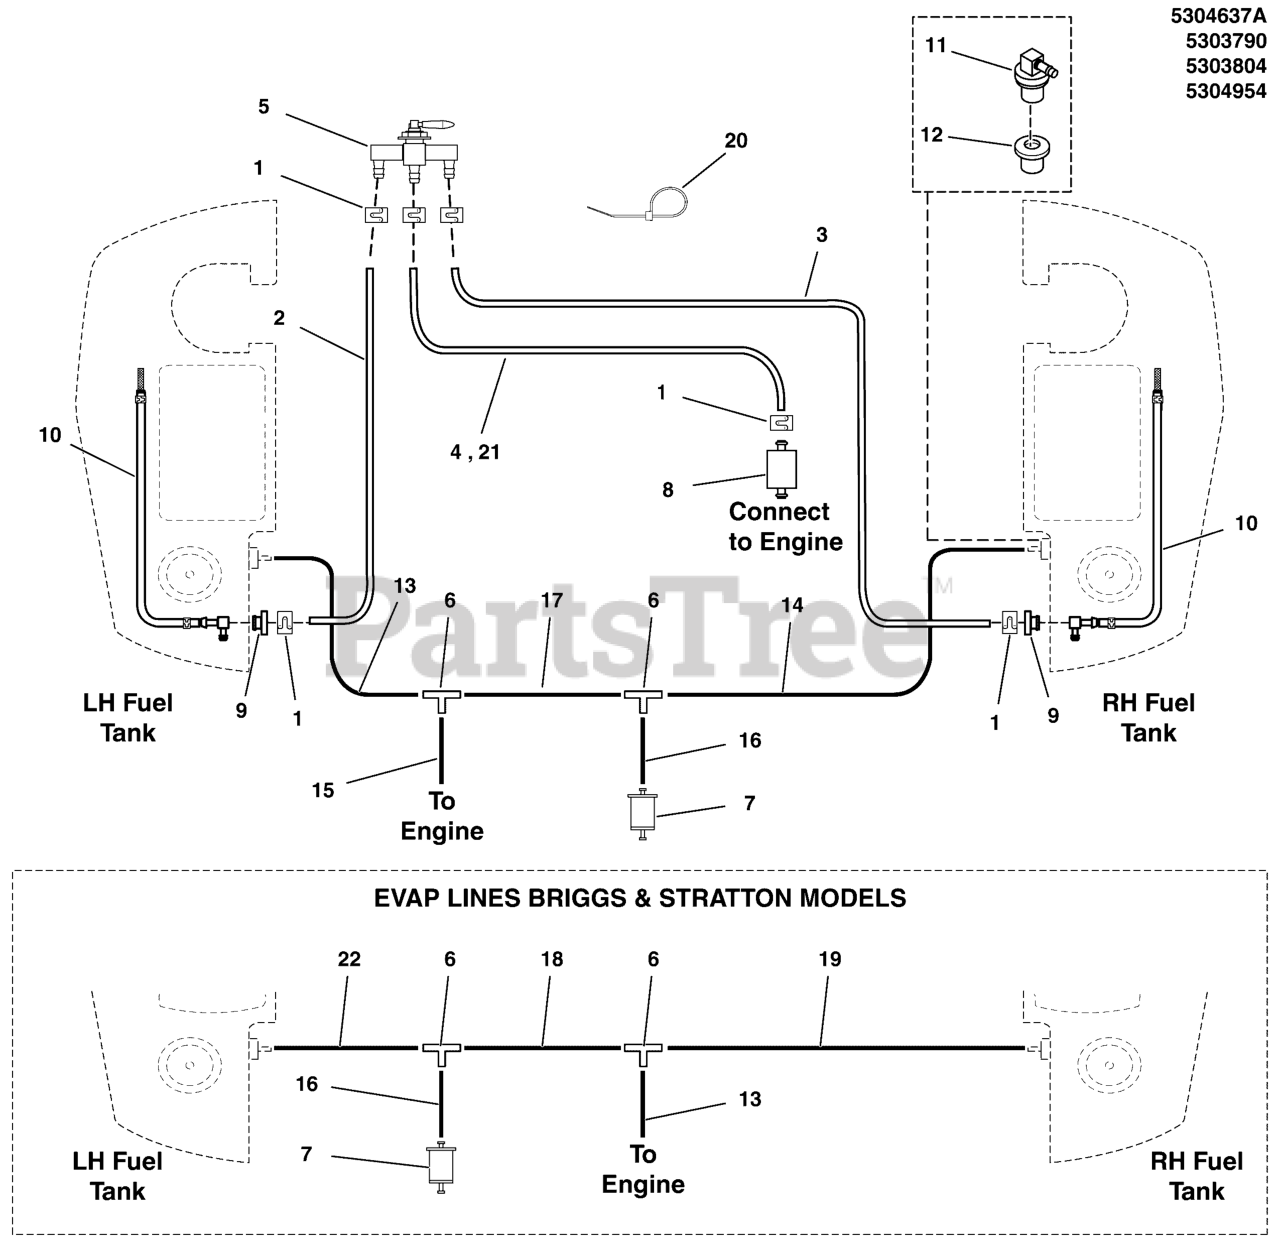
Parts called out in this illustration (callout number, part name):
1	CLAMP, Hose
2	HOSE, FUEL, 1/4 IN, LW PRMTN, 24" LONG
3	HOSE, FUEL, 1/4 IN, LW PRMTN, 26" LONG
4	HOSE, FUEL, 1/4 IN, LW PRMTN, 16" LONG
5	SEE FUEL TANK AND MOUNT GROUP
6	FITTING, 3/16" TEE, BARB TYPE, HDPE
7	FILTER, FUEL
8	FUEL FILTER (SV)
9	BUSHING-FUEL TANK RED RUBBER
10	PICKUP TUBE ASM, FUEL TANK, 23" (SV)
11	REMOTE VENT ASSEMBLY
12	GROMMET (SV)
13	HOSE, VAPOR, 5MM ID, 12.00 LG
14	HOSE, VAPOR, 5MM ID, 21.00 LG
15	HOSE, VAPOR, 5MM ID, 16.50 LG
16	HOSE, VAPOR, 5MM ID, 2.00 LG
17	HOSE, VAPOR, 5MM ID, 17.50 LG
18	HOSE, VAPOR, 5MM ID, 5.00 LG
19	HOSE, VAPOR, 5MM ID, 22.00 LG
20	TIE, SELF-LOCKING, 6"
21	1/4" Fuel Line, 5" Long
22	HOSE, VAPOR, 5MM ID, 26.00 LG
